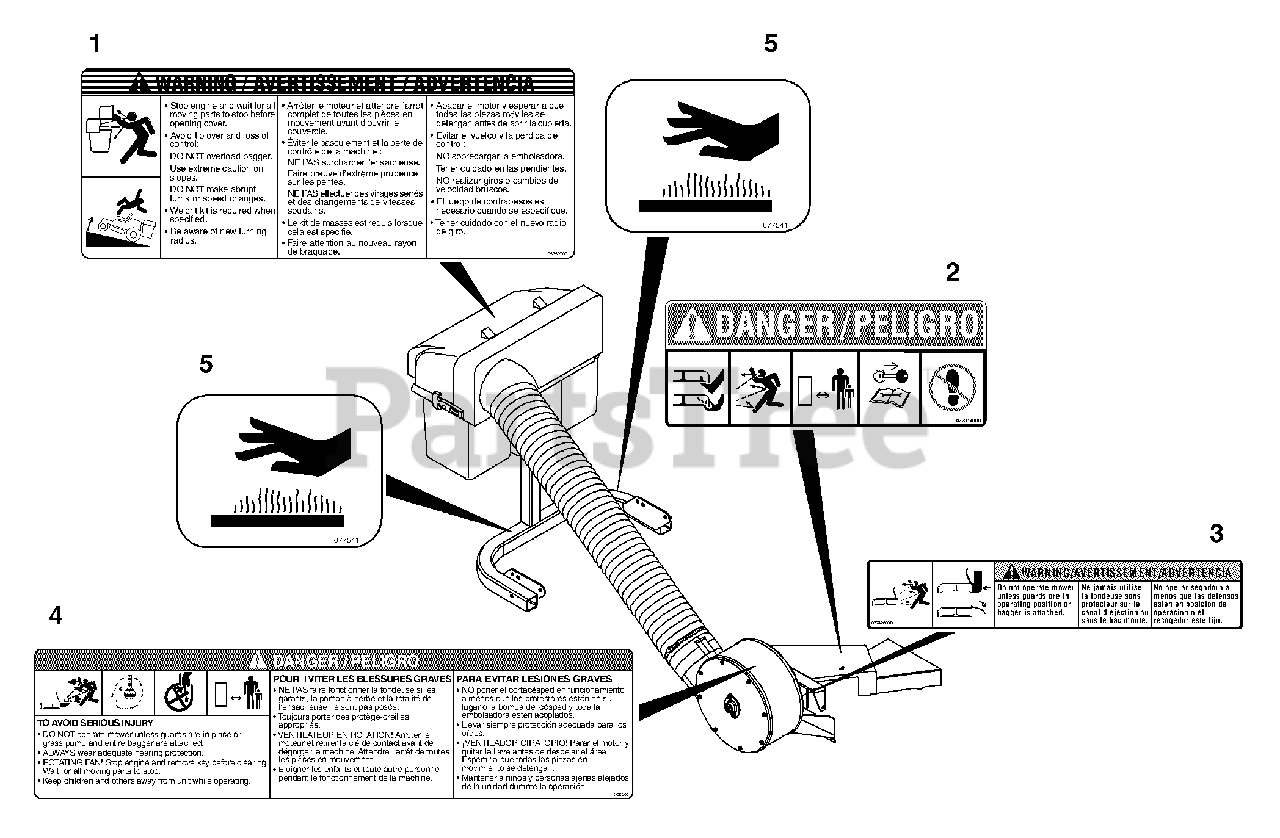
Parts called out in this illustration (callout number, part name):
1	Decal-Warning, Bagger Cover
2	Decal, Mower Pan Head Danger
3	Decal, Warning
4	Decal-Caution, Grass Pump
5	Decal, Hot Surface
